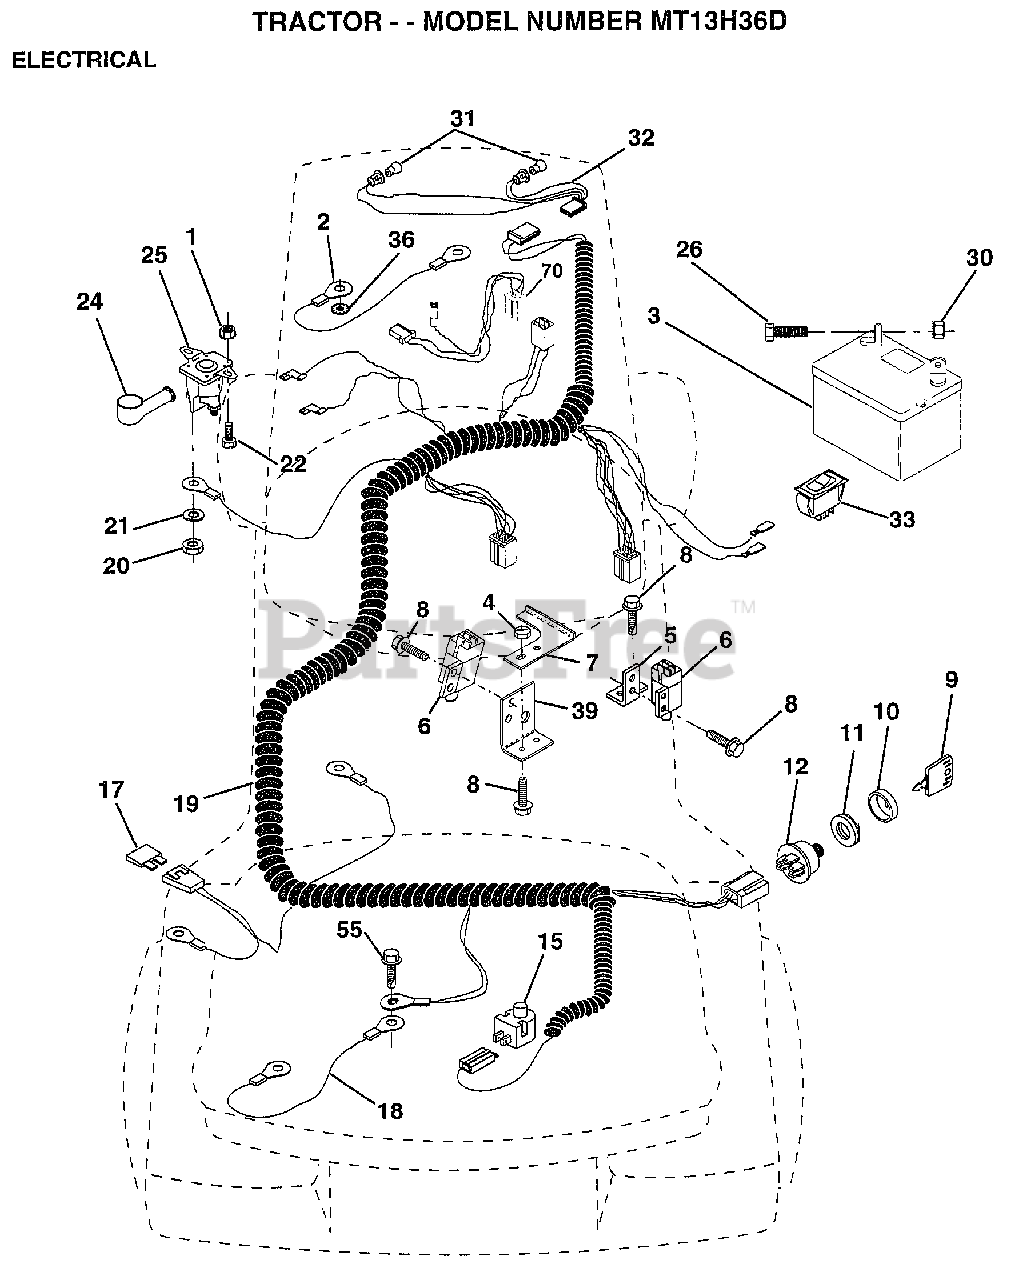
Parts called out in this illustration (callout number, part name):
1	NUT HXKEP 1/4X20
2	CABLE ASM.
4	LOCKNUT
5	BRACKET LT
6	SWITCH INTERLOCKT
7	KEEPER.ACTUAT.LR.
8	SCREW
9	KEY MLD GEN DELTA
10	COVER KEY SWITCH
12	SWITCH.IGNITION
15	SWITCH SEAT
17	FUSE.15 AMP
18	CABLE ASSY
19	HARNESS.IGNITION
20	NUT
22	BOLT HXHD FIN
26	BOLT LT
30	NUT
31	HEADLAMP BULB
32	HARNESS.ASM.LIGHT W/4152J
33	SWITCH LT
36	LOCKWASHER
39	BRACKET SWT CLUTC
55	SCREW LT
70	HARNESS.ENGINE
